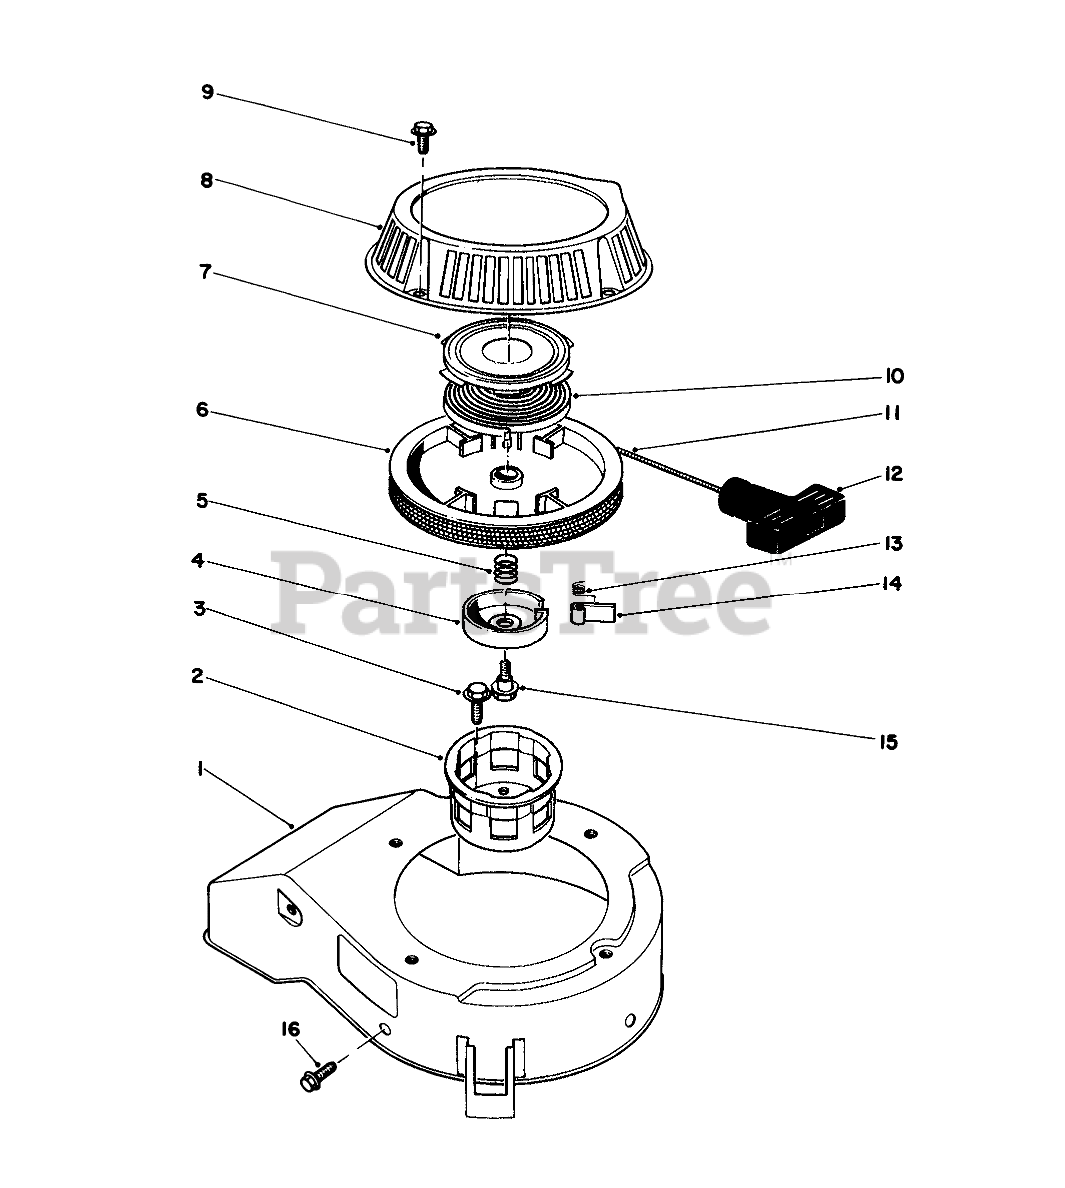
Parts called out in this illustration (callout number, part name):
1	COVER
2	CUP - STARTER
4	RETAINER
5	SPRING
7	Retainer-Recoil Spring
9	SCREW-HHF
10	Spring-Recoil
11	ROPE-STARTER
12	HANDLE-RECOIL
13	SPRING
